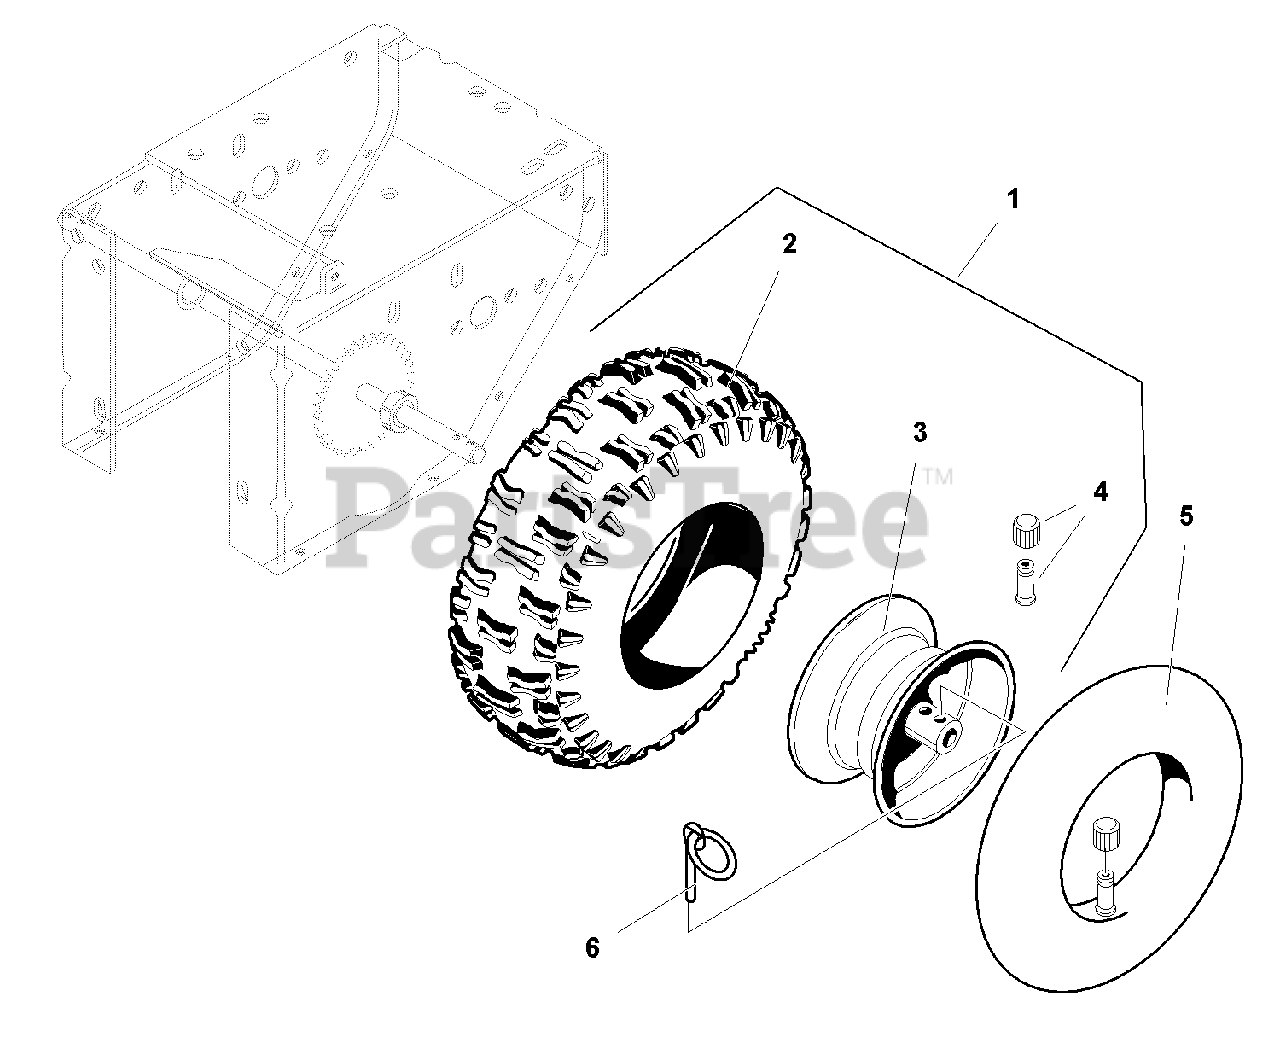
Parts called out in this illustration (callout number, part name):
1	WHEEL & TIRE ASSEMBLY (Includes Ref. Nos. 2, 3 & 4)
2	TIRE, 4.80-4.00-8
3	HUB, Wheel R.H., 3-3/4 Wide 8 Diameter 3/4 ID
4	VALVE STEM & CAP
